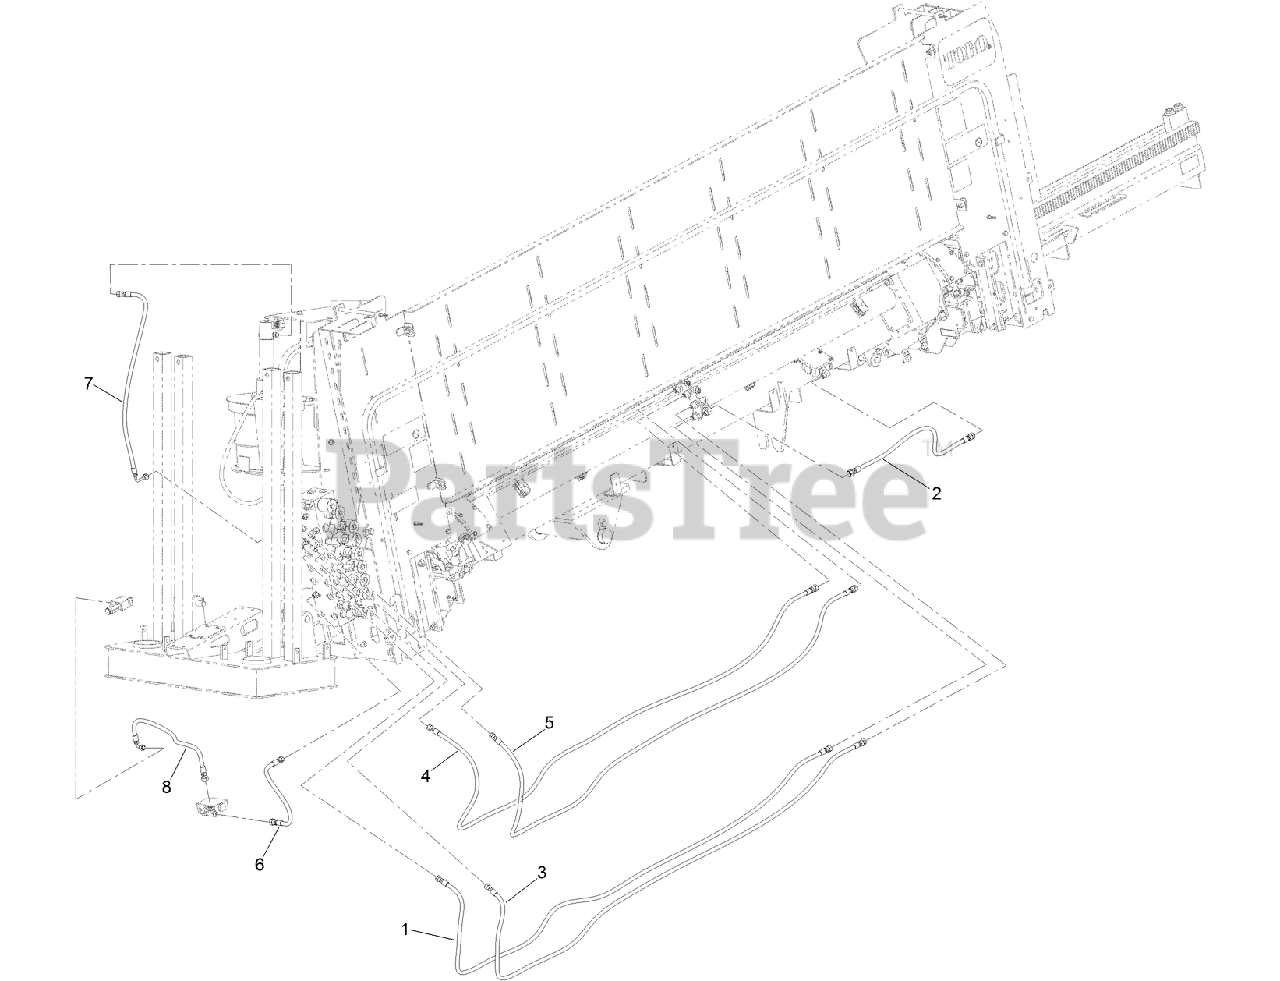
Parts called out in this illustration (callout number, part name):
1	HOSE ASM
2	HOSE ASM
3	HOSE ASM
4	HOSE ASM
5	HOSE ASM
6	HOSE ASM
7	HOSE ASM
8	HOSE ASM
